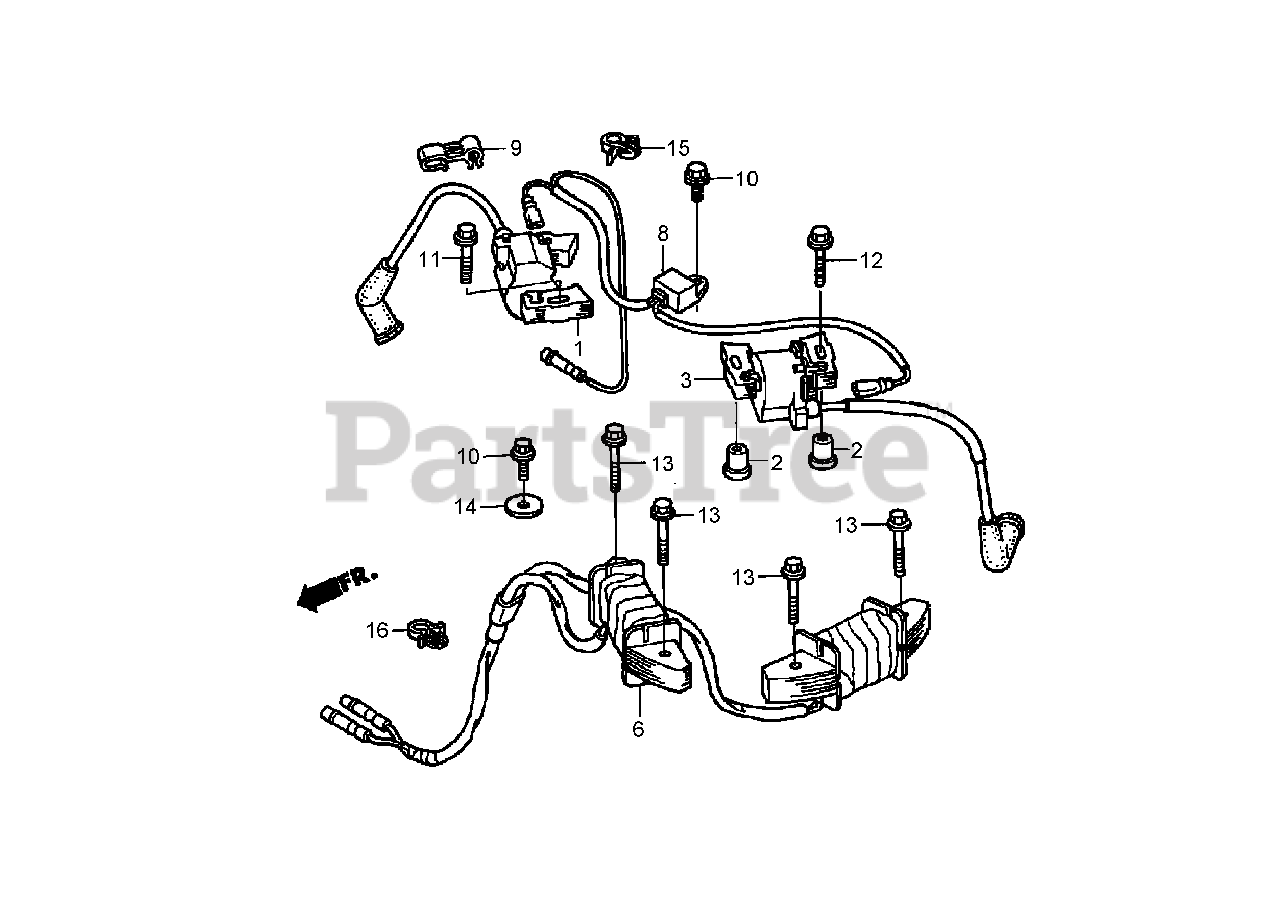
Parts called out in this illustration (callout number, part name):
1	IGNITION COIL ASM (No. 1)
2	COLLAR-COIL, IGNITION
3	IGNITION COIL ASM (No. 2)
6	CHARGE COIL ASM (12V-12A)
8	ENGINE STOP DIODE ASM
9	CLAMP-WIRE, CENTER
10	BOLT-FLANGE (6X12) (C T200)
11	BOLT-FLANGE (6X28)
12	BOLT-FLANGE (6X45) (C T200)
13	BOLT-FLANGE (6X32)
14	WASHER-SETTING, TANK
15	CLIP-HARNESS, WIRE (6MM) (WHITE)
16	CLIP-HARNESS, WIRE
